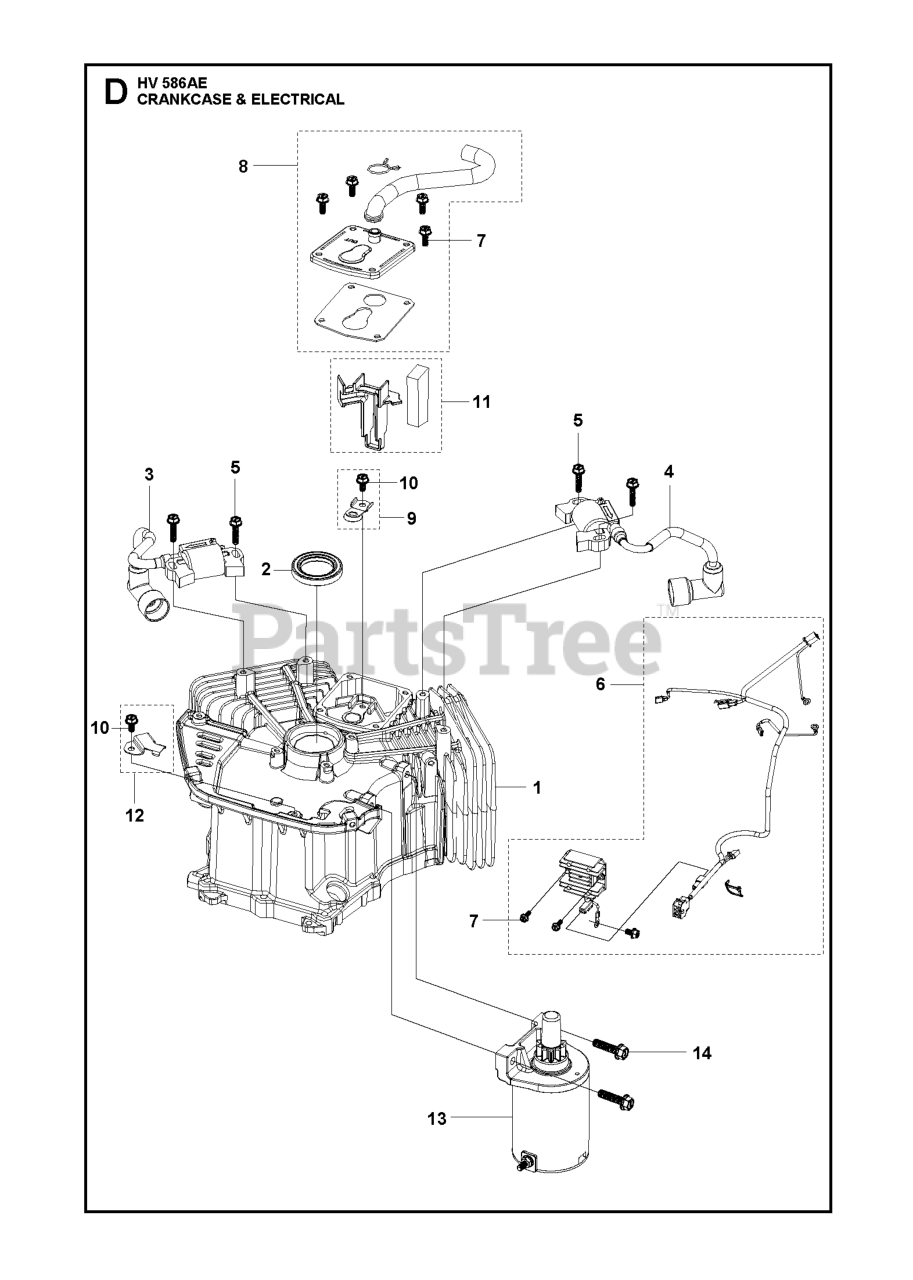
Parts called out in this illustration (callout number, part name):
2	SEAL OIL SEAL
5	BOLT GB/T 5789: M6 L=25
10	BOLT GB/T 5789: M6 L=12
